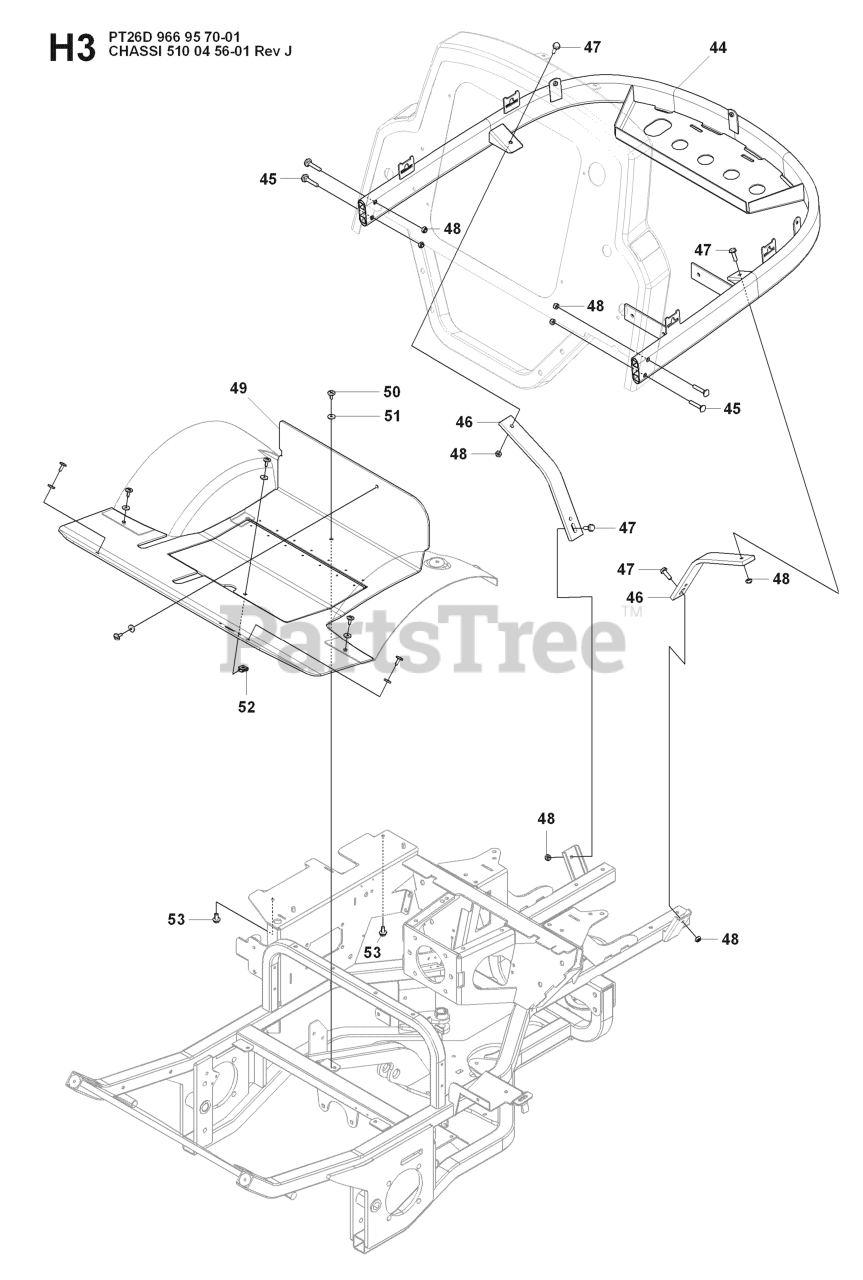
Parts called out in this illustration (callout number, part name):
45	Screw Mvbf 8 X 40
47	BOLT
48	LOCKNUT M8
